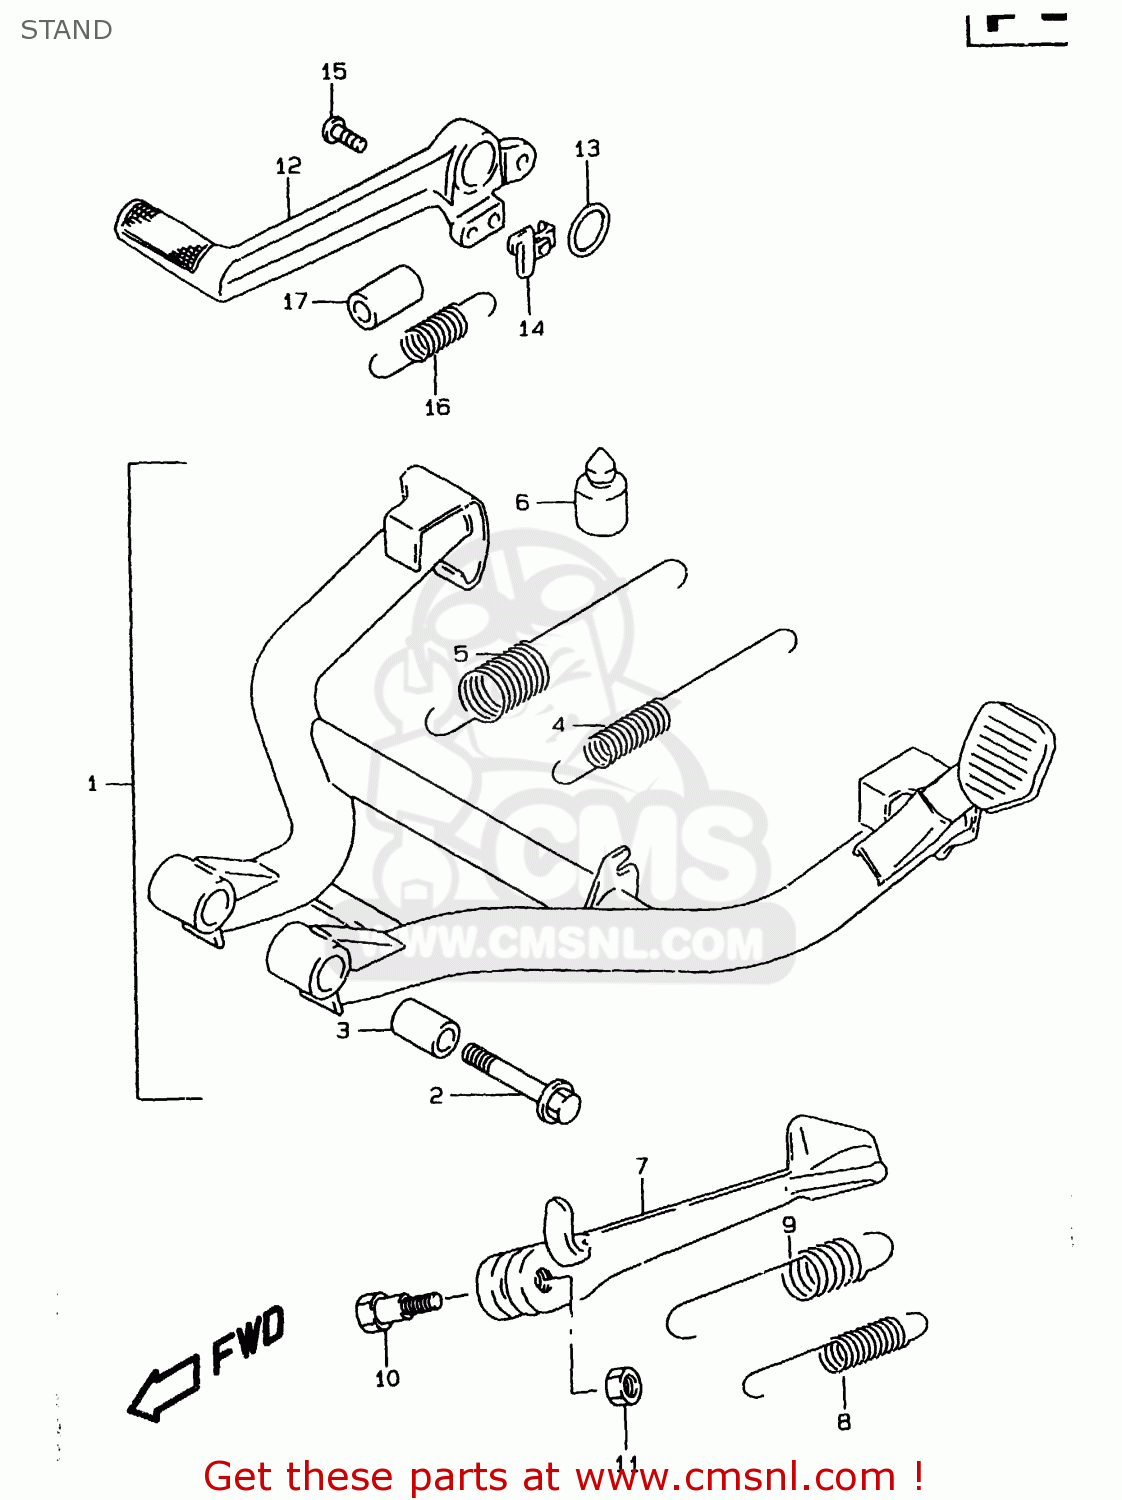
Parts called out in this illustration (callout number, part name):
1	STAND,CENTER
2	BOLT(10X48)
3	SPACER(10X16X25.5)
4	SPRING
5	SPRING OUTER
6	CUSHION
7	STAND,PROP
8	SPRING
9	SPRING
10	BOLT(10X34)
11	NUT
12	PEDAL,BRAKE
13	WASHER(18X24X1)
14	BRACKET,STOP LAMP SWITCH SPR
15	SCREW
16	SPRING
17	TUBE,BRAKE SPRING GUIDE
